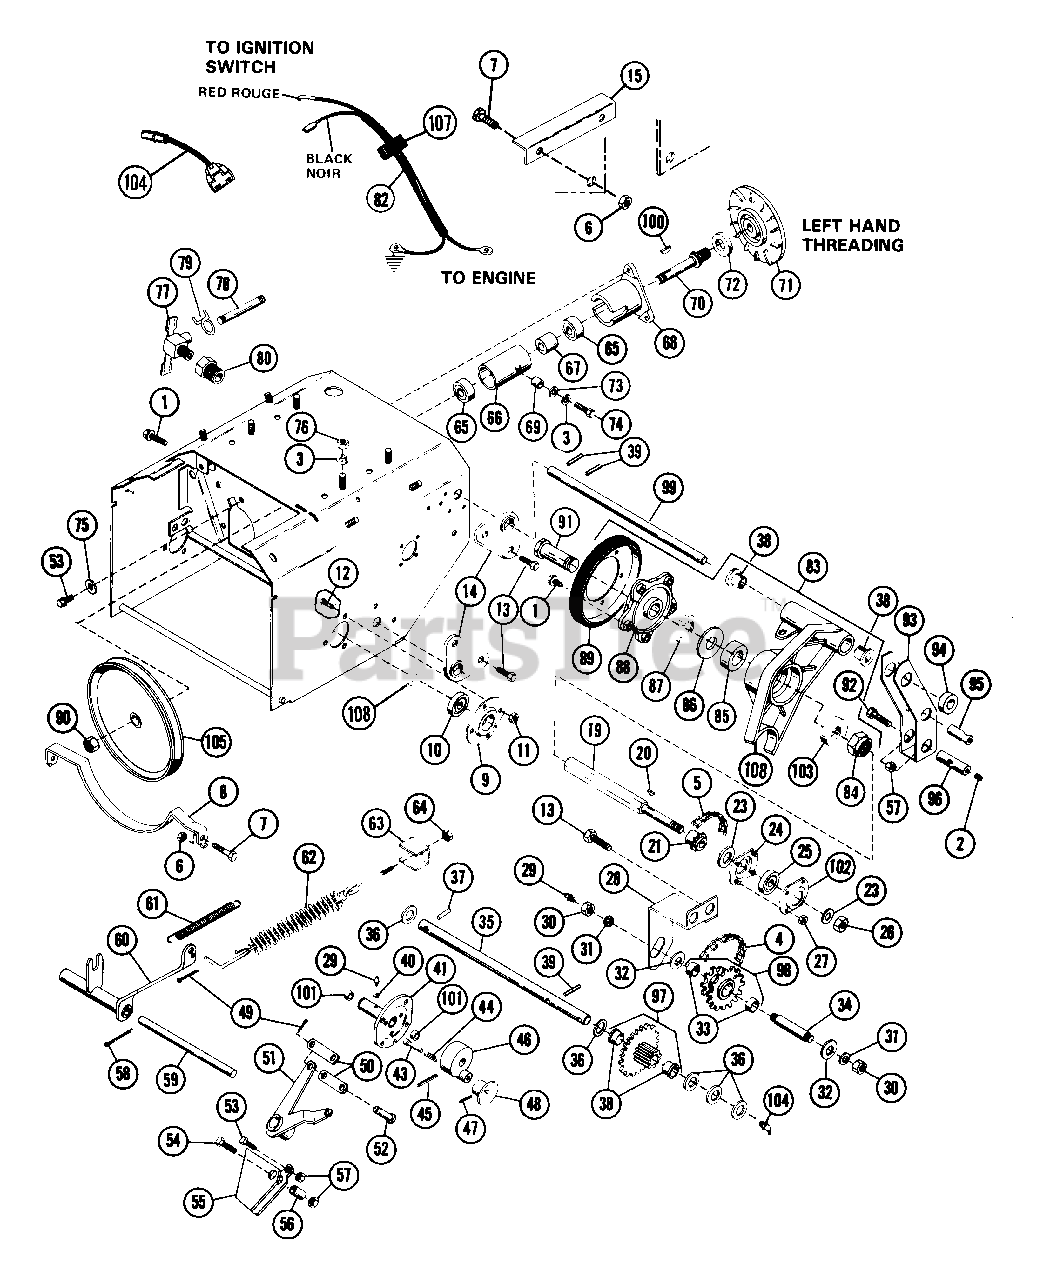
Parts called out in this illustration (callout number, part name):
1	BLT-SERHFWH .31-18X.50 PL
2	SCR-SET .32-18X.38 SKHCUPNL OH
3	WSHR-LK .312X.097 PL HVY
4	PINION CHAIN
5	IDLER CHAIN
6	NUT-LK-CTR .250-20 PL
7	BLT-HEX .25-20X.50 PL GR2
8	BELT RETAINER
9	BEARING RETAINER
10	BRG-BALL 1.13X2.18X.63
11	NUT-LK-FLG .250-20 PL
12	BLT-SERNK SL .25-20X.50 PL
13	BLT-SERHFWH .25-20X.50 PL
14	SUPPORT, SHAFT
16	CARRIER
17	WIRE CLIP
18	PLY-V 8.00 X 1.0 W/KEY CLARK
19	HEX SHAFT
20	KEY-WDRF .125X.625X.250 SAE5
21	9 TOOTH SPROCKET
22	HYDRAULIC DRIVE FITTING
23	WSHR-FL-STL .505X1.000X.062
24	BEARING FLANGE
25	BRG-BALL .500X1.38X.437
26	NUT-LK-CTR .50-20 PL
27	NUT-LK DUAL FACE 10-24 PL
28	SUPPORT, SHAFT
28	CLUTCH STOP
29	SPIN DRIVE ZERK FITTING
30	NUT-HEX .375-16
31	WSHR-LK .375X.130
32	WSHR-FL-STL .382X.812X.062
33	BSHG-SLV .500X.625X.500 BR
34	REDUCTION SHAFT
35	PINION SHAFT
36	WSHR-FL-STL .630X1.005X.062 PL
37	PIN-ROLL .125X1.00
38	BSHG-FLG .625X.750X.500X.875BR
39	PIN-ROLL .156X1.00
40	WSHR-LK .250X.047 LT PL
41	L H AXLE ASSEMBLY
42	BSHG-SLV .562X.625X.625 BRZ
44	SG-COMP .028X.34X1.062 WLD75
45	PIN-GRV .250X1.75 TP C
46	LOCKOUT HUB
47	PIN-ROLL .093X1.00
49	PIN-COTR .09X.75 PL
50	SHIFT LINK
51	LEVER - SHIFT ARM
52	CLEVIS PIN
53	BLT-HEX .31-18X.50 PL GR2
54	BLT-HEX .31-18X3.00 PL GR2
55	BRACKET SHIFT LEVER
56	SPACER .5 X .33 X 2.4
57	NUT-LK .312-18 GR A PL
58	PIN-COTR .09X1.0 PL
59	ROD, FORK PIVOT
60	FORK, CLUTCH
61	SG-TENS .080X.73X3.06 WLD 20
62	SPRING ASSEMBLY
63	ADAPTER SPACER
64	NUT-LK-NYL.312-18 PL
65	BRG-BALL .625X1.375X.44
66	SPINDLE HOUSING
67	BEARING SPACER
68	DRIVE SPINDLE HOUSING
70	SPINDLE
71	DRIVE PLATE
72	DRIVE DISC SPACER 1.3X.76X.19
73	WSHR-FL-STL.344X.688X.065PL
74	BLT-HEX .31-18X1.00 PL GR 2
75	WSHR-LK-INT .313X.030 PL
76	NUT-HEX .312-18
77	DRAIN LOCK
79	HOSE CLAMP
80	BUSHING
81	SNAP BUSHING-.437
82	SHORTING WIRE
83	FRICTION WHEEL ASSEMBLY
84	NUT-LK-NYL .875-14
85	BRG-BALL .876 X 1.750 X .50
86	WSHR-FL-STL .880X1.250X.062
87	RG-RTNG-INT 1.750X.062
88	SPINDLE HUB
89	FRICTION DISC
90	NUT-LK-NYL.625-18 PL
91	SPINDLE HUB
92	BLT-HEX .31-18X.75 PL GR2
93	CLUTCH ENGAGEMENT YOKE
94	SPACER 1.00 X .64 X .38
95	ADAPTER
96	ROD ADAPTER
97	PINION & SPROCKET ASSEMBLY
98	SPROCKET ASSY
99	CARRIER SHAFT
100	KEY-WDRF .125X.500X.203 SAE 3
101	BSHG-SLV .750X.814X .750 BRZ
102	BEARING FLANGE
103	BSHG-SLV .882X1.250X.531
107	WIRE CLIP
108	WSHR-FL-STL .625X1.469X.109PL
